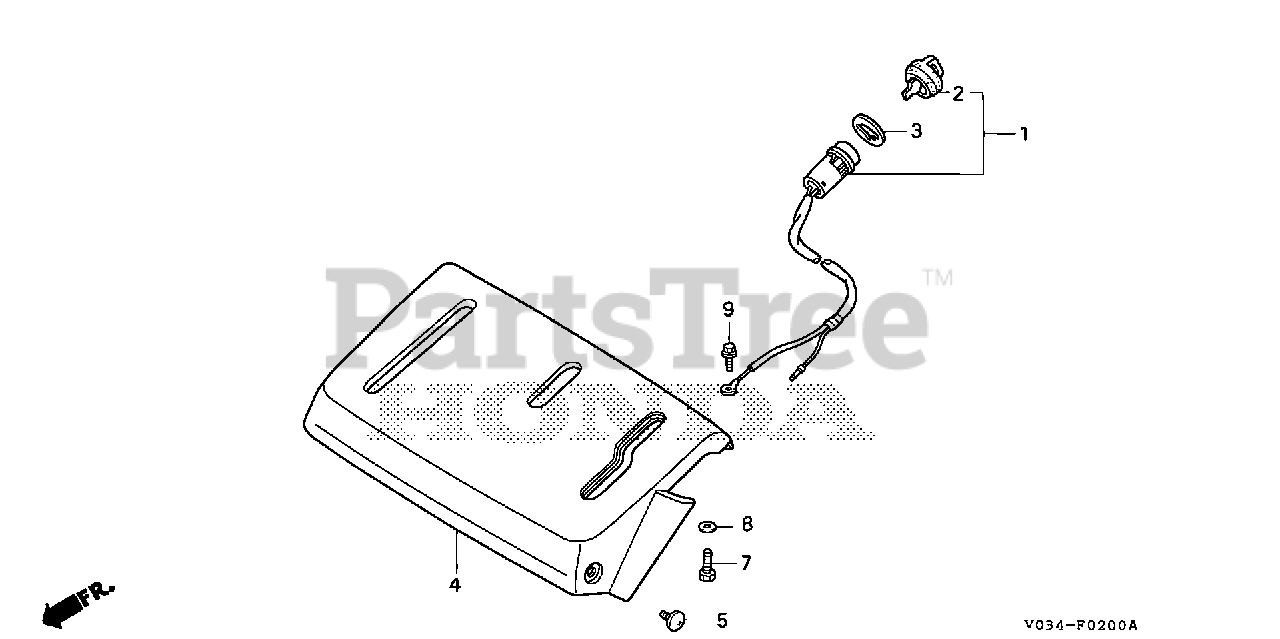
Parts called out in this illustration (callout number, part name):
1	SWITCH ASSY., COMBINATION
2	KEY ASSY., COMBINATION SWITCH (RED)
3	SPACER, ENGINE STOP SWITCH
4	PANEL, CONTROL *NH296* (ALPS GRAY)
5	BOLT, CONTROL PANEL
5	SCREW, METER VISOR SETTING
7	BOLT, FLANGE (5X12)
7	BOLT, HEX. (5X12)
8	WASHER, PLAIN (5MM)
9	BOLT, FLANGE (6X10)
